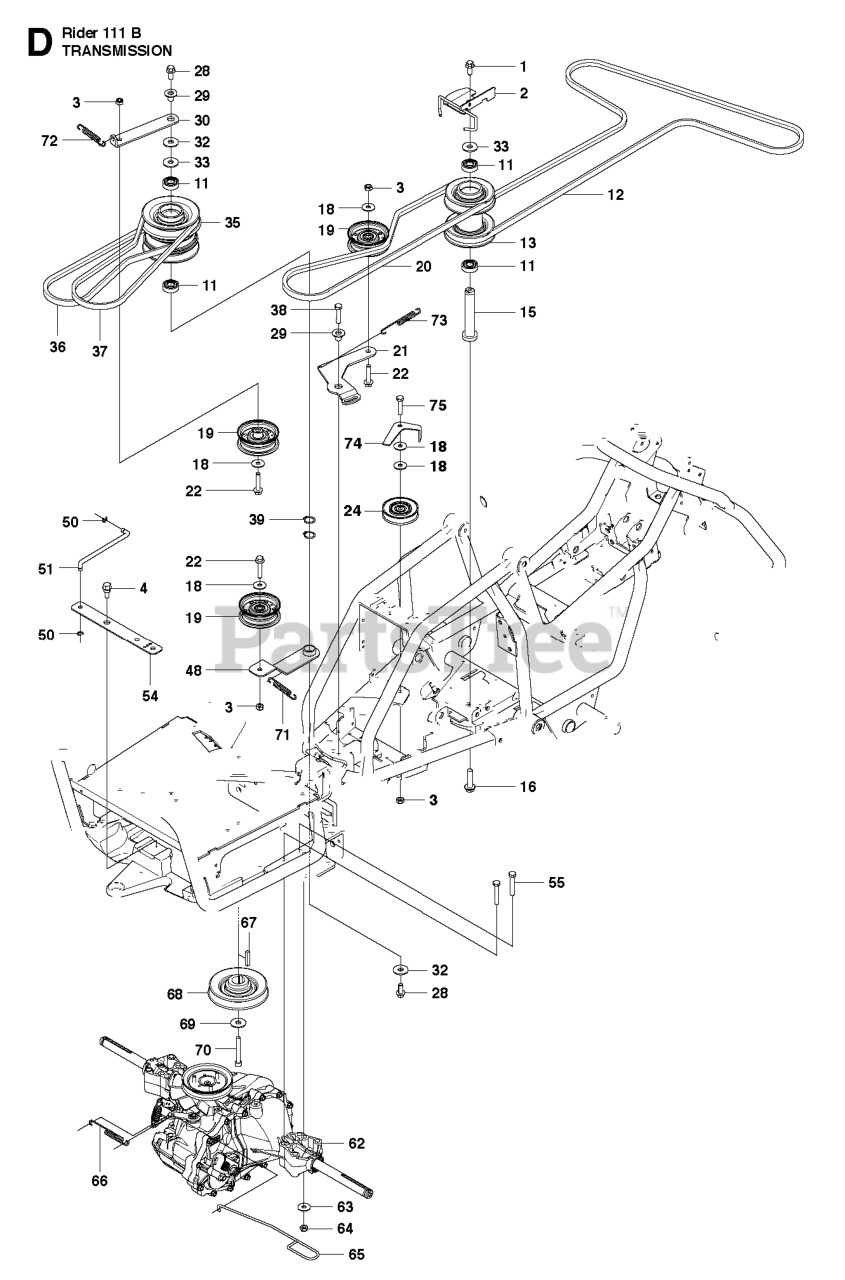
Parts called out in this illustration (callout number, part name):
3	LOCKNUT M8
11	BALL BEARING 6004-2RS1
19	IDLER PULLEY
21	BELT TENSIONER
28	BOLT
29	WASHER
38	BOLT
39	RETAINING RING SGA 20
63	WASHER BRB 8.4X17
64	NUT
